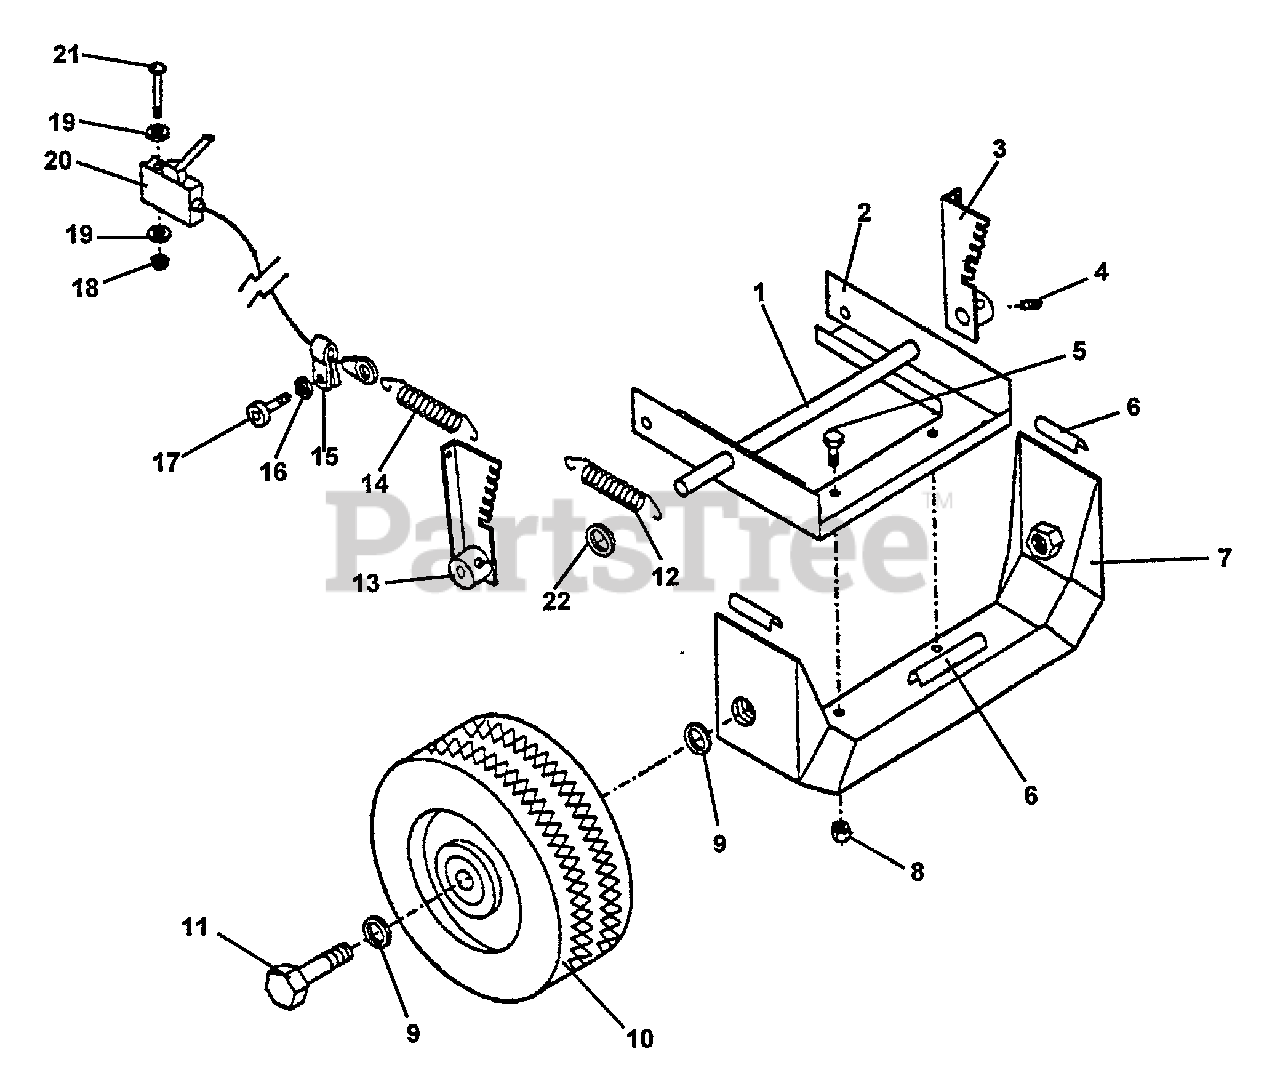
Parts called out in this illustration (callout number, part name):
9	Washer 5/8 SAE-FLAT
11	BOLT - 5/8-11 X 4-1/2"
16	LOCKWASHER - 10
19	WASHER - 6
21	SCREW - 6/32 X 2"
